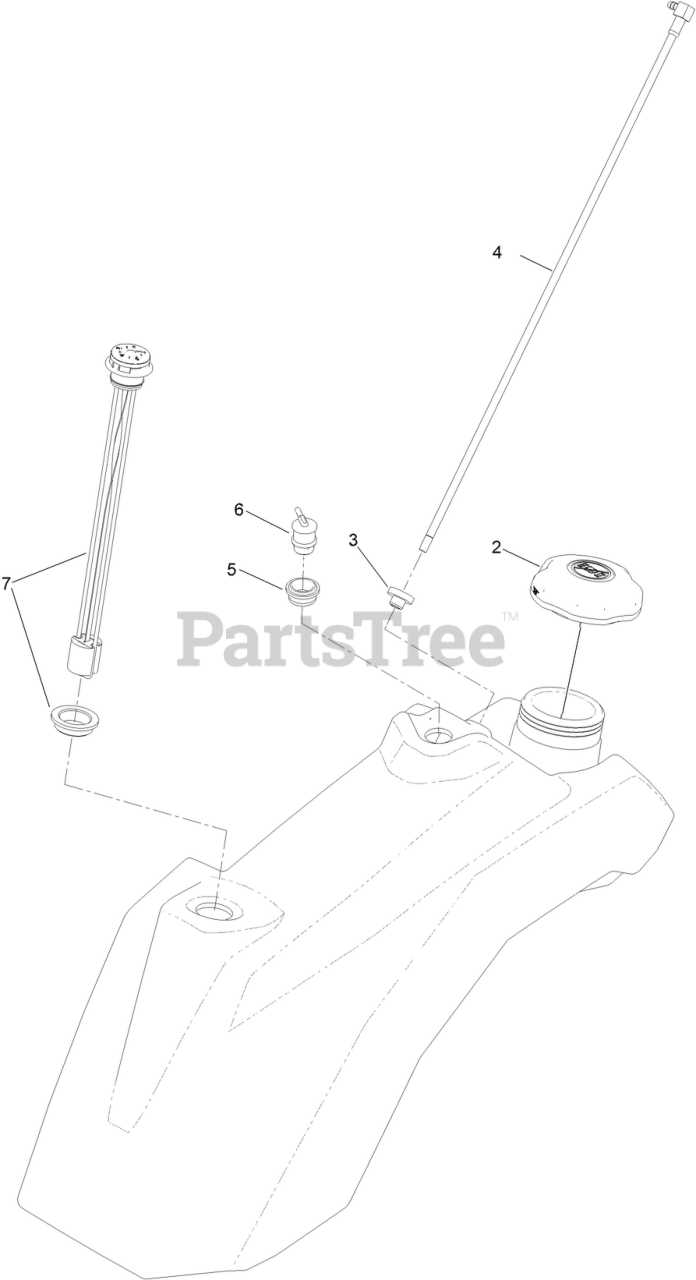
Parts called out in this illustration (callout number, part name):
2	CAP-FUEL, RATCHETING
3	BUSHING
4	STRAW, FUEL, LONG
5	GROMMET
6	VALVE-VENT, FUEL
7	ASM-FUEL GAUGE
